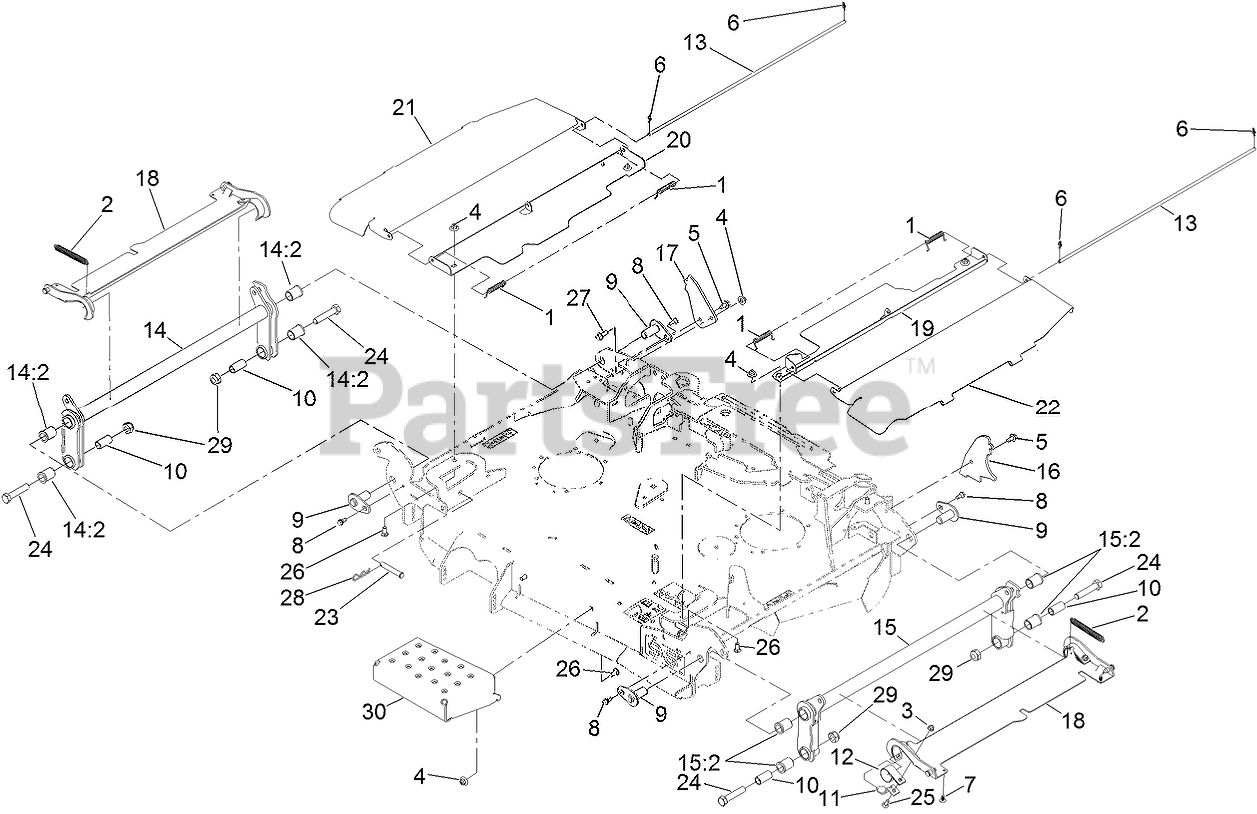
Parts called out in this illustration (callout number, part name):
1	SPRING-TORSION
3	NUT-HF, NI
4	Nut-Nyloc 3/8-16 Flg
5	SCREW-HWH
6	PIN-COTTER, LOCKING
7	PLUG-PLASTIC
8	SCREW-SHOULDER
9	PIN-DECK
10	BUSHING-FLOAT, DECK
11	PLATE-RETAINER, BEARING
12	BEARING-STRAP, NYLON
13	COVER-ROD, PIVOT
14	RH FOLD ARM ASM
14:2	BUSHING-FLANGED
15	LH FOLD ARM ASM
15:2	BUSHING-FLANGED
16	BRACKET-DECK STOP, LH
17	BRACKET-DECK STOP, RH
18	COVER-WING
19	SHIELD-CENTER, LH
20	SHIELD-CENTER, RH
21	Panel-Shield Hinge, LH
22	Shield-Center, RH
23	PIN-CLEVIS
24	SCREW-HH
25	SCREW-CARR
26	BOLT-CARR
27	SCREW-HHF 3/8-16 X 1
28	PIN-HAIR
29	NUT-LOCK
30	Panel-Step
